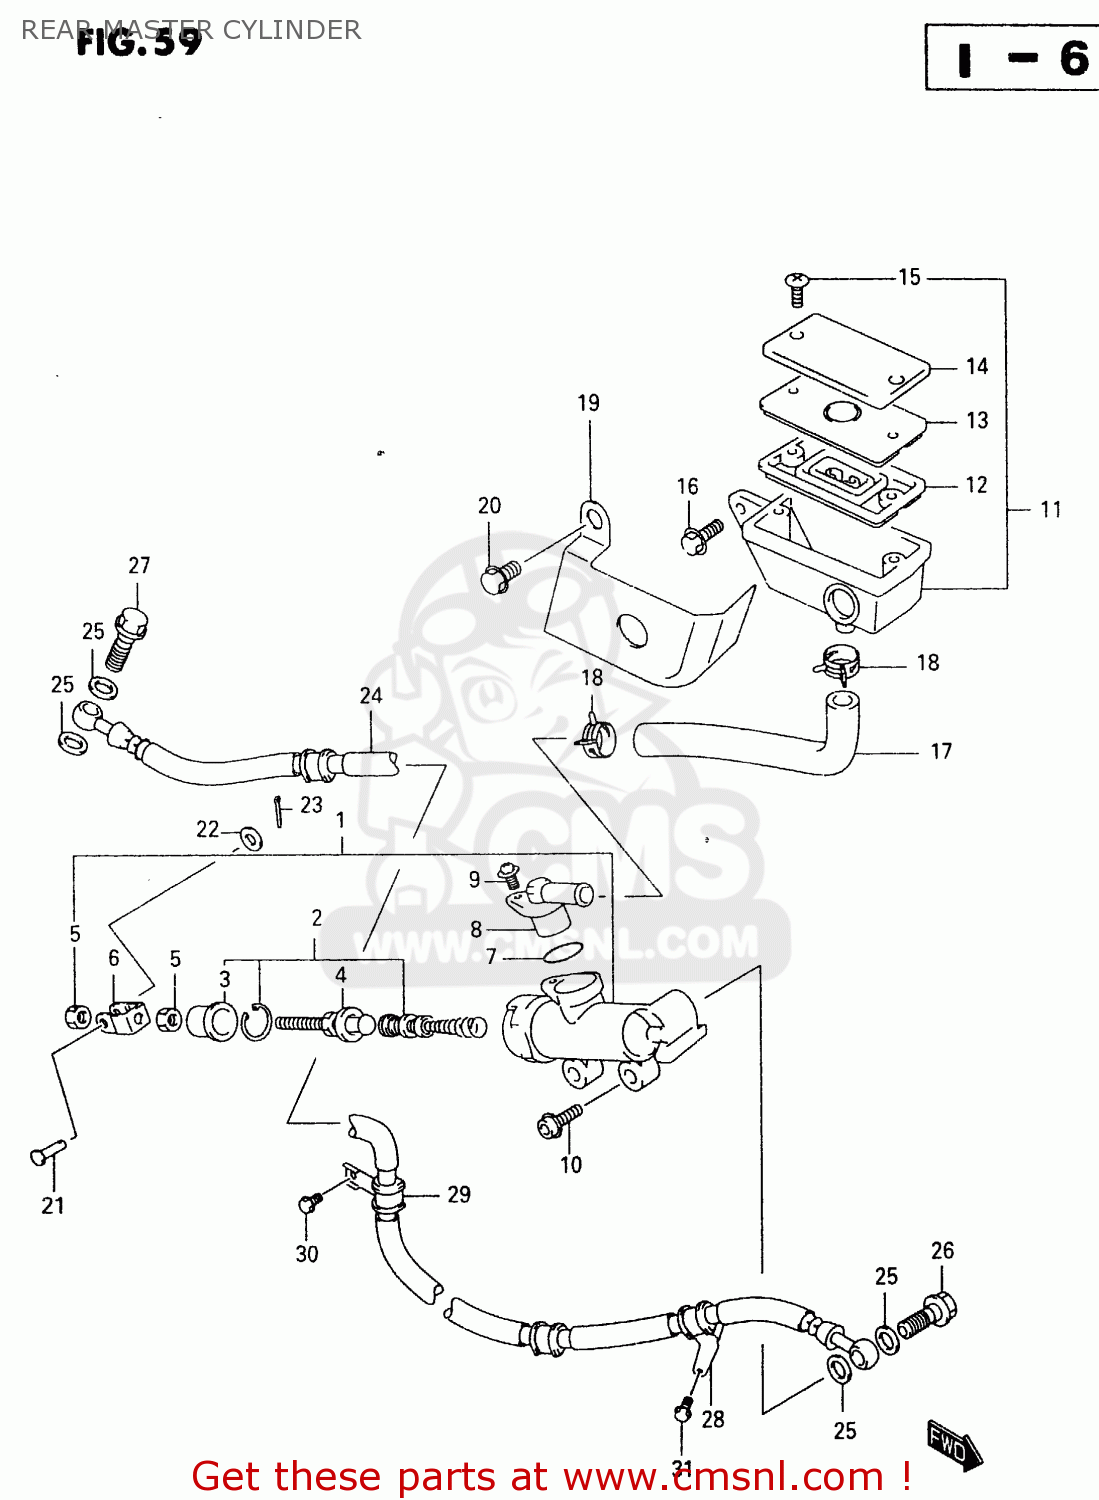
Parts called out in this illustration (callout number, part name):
1	CYLINDER ASSY,RR MASTER
2	PISTON/CUP SET
3	BOOT
4	ROD,PUSH
5	NUT
6	YOKE
7	O RING
8	CONNECTOR
9	SCREW
10	BOLT MAGNETO S
11	TANK ASSY,RR RESERVOIR
12	13
13	PLATE,DIAPHRAGM
14	CAP
15	SCREW
16	BOLT
17	HOSE,RESERVOIR TANK
18	CLIP
19	COVER,RESERVOIR TANK
20	BOLT
21	PIN
22	WASHER
23	PIN
24	HOSE,RR BRAKE
25	WASHER(10X15X1.5)
26	BOLT UNION
27	BOLT UNION
28	CLAMP,RR BRAKE HOSE NO.1
29	CLAMP,FRONT BRAKE NO.2
30	BOLT
31	BOLT
